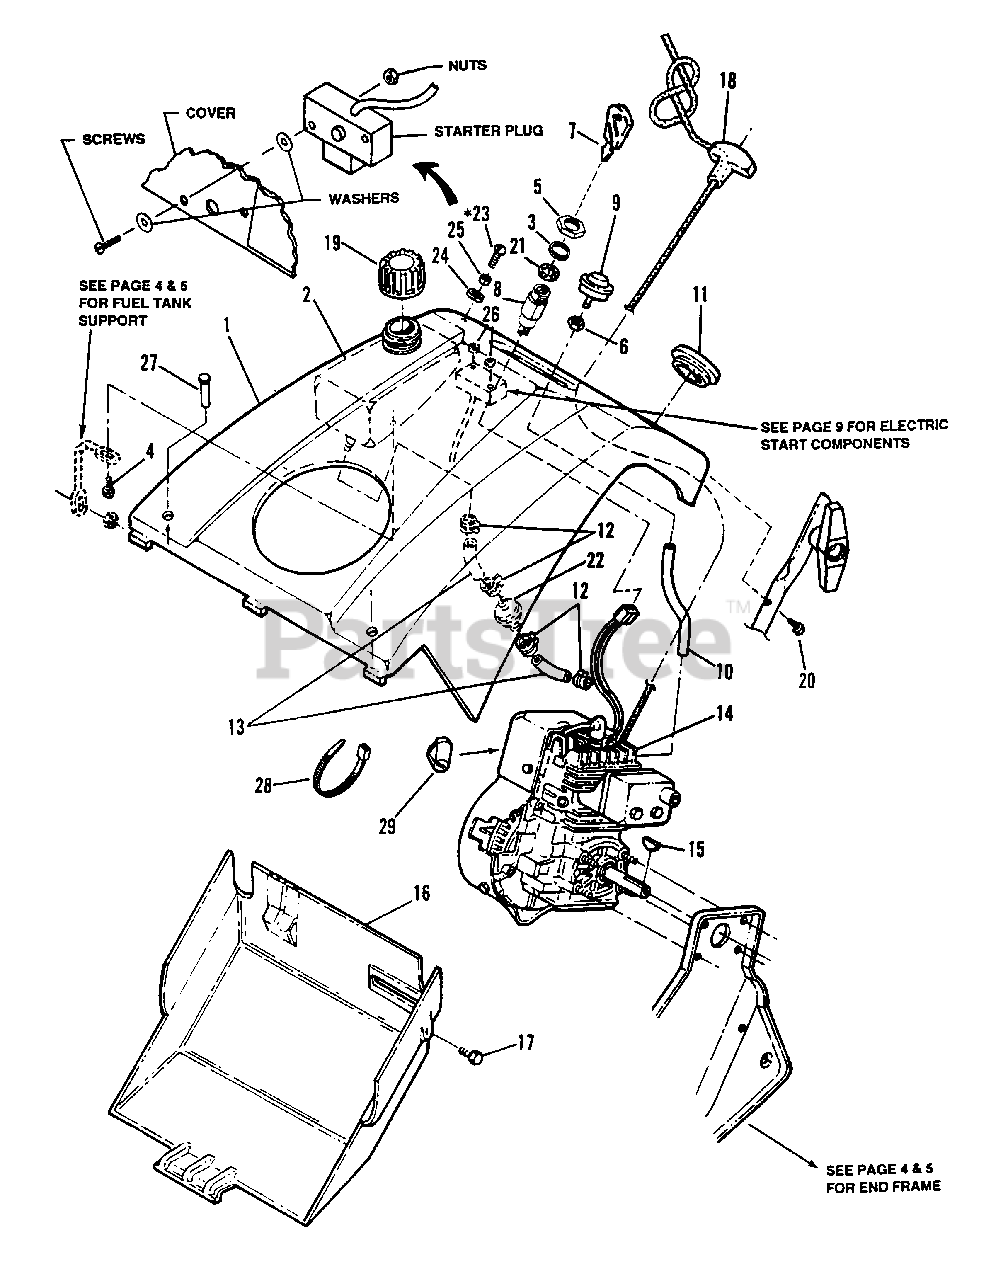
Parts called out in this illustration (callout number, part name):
1	COVER, Top
2	ASSEMBLY, Fuel Tank
3	SPACER
4	SCREW, 1/4-20 x 1/2" Machine
5	NUT, 5/8-32 Hex
6	NUT, 1/4-20 Hex Flange Lock
7	KEY
8	SWITCH, Ignition
9	PRIMER
10	HOSE, Primer
11	PLUG, Hole
12	CLAMP, Fuel Hose
13	HOSE, Fuel 8-1/2" Long
14	* ENGINE, 3 HP (TEC HSK600-1702W)
15	KEY, 5/32 x 5/8" Woodruff
16	COVER, Bottom
17	SCREW, #10-24 x 1/2" Hex Washer Self-Tap (Torx)
18	HANDLE, Pull Rope
19	CAP, Fuel Tank
20	SCREW, 08-18 x 1-1/2" Self-Tapping
21	WASHER, 5/8 Internal Tooth Lock
22	FILTER, In-Line
23	SCREW, 1/4-20 x 3/4" Self-Tapping (Torx)
24	ISOLATOR, Fuel Tank/Cover
25	SPACER
26	WASHER, #10 Flat
27	PIN, Clevis 1/4 x 5/8"
28	CABLE TIE
29	KNOB, Red
